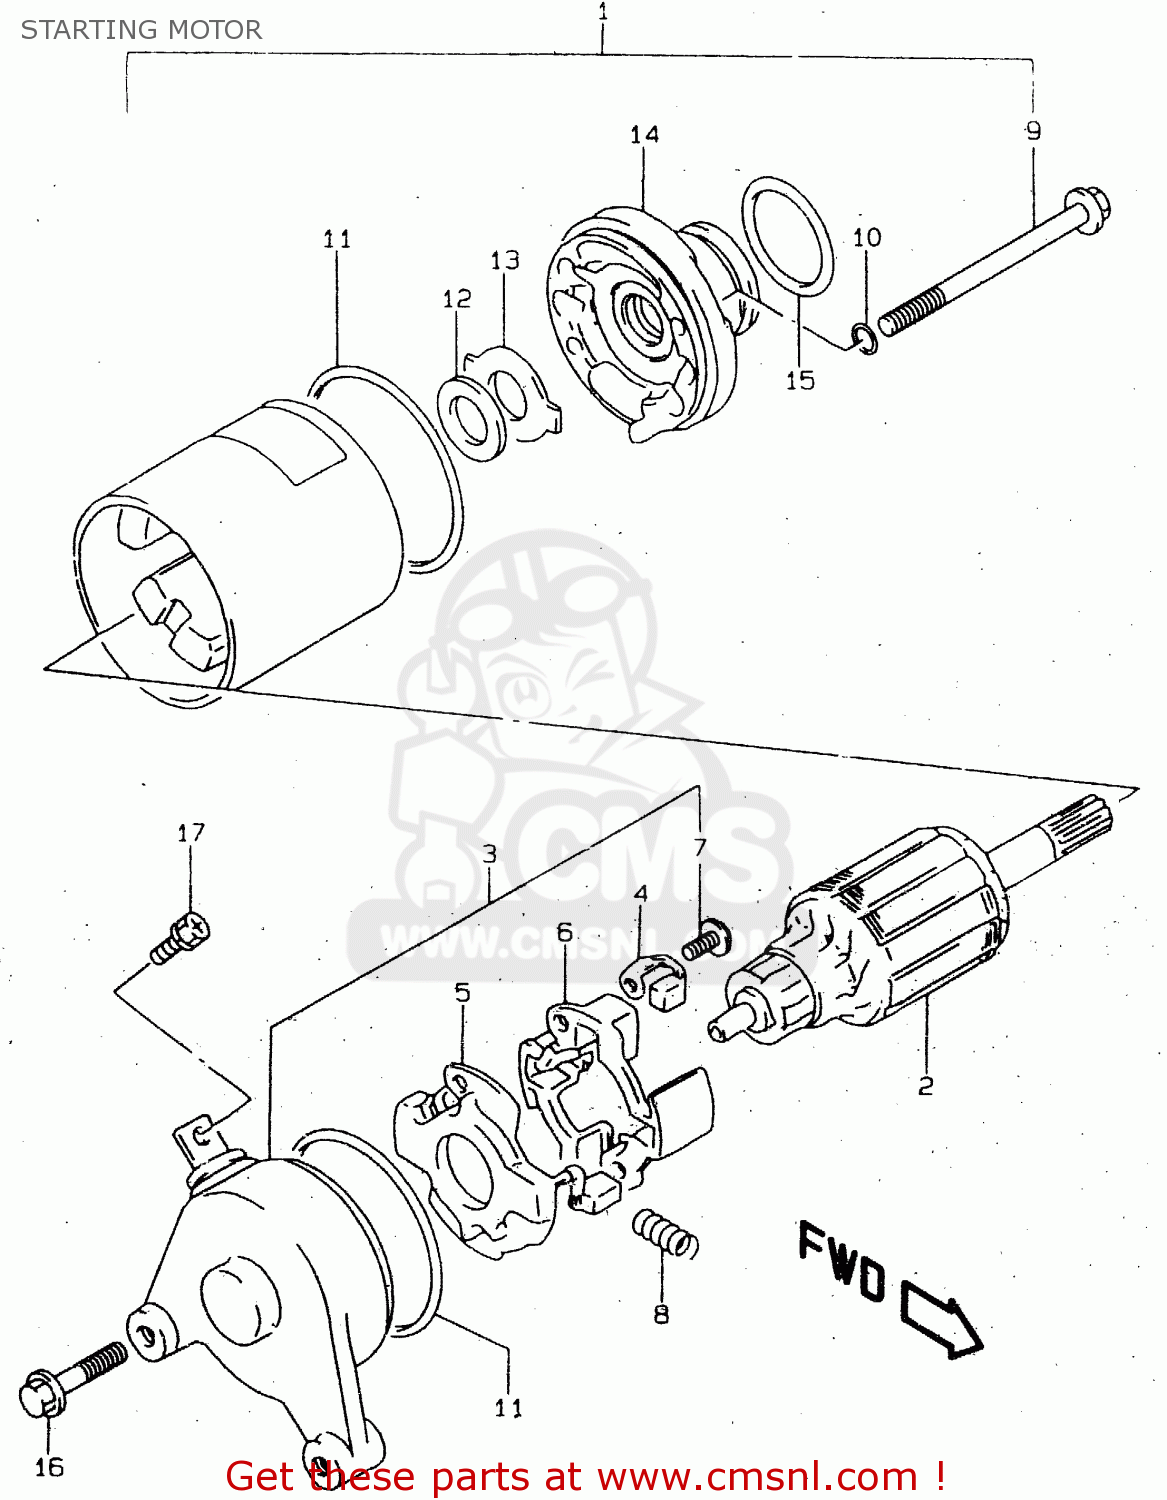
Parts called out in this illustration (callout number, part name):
1	MOTOR ASSY,STARTING
2	ARMATURE
3	FRAME ASSY,COMMUTATOR END
4	BRUSH
5	BRUSH SUB ASSY,STARTER
6	HOLDER,BRUSH
7	SCREW
8	SPRING
9	BOLT
10	O RING
11	O RING
12	SHIM
13	PLATE,LOCK
14	BRACKET
15	O RING(D:3,ID:24.5)
16	BOLT
17	SCREW(5X8)
